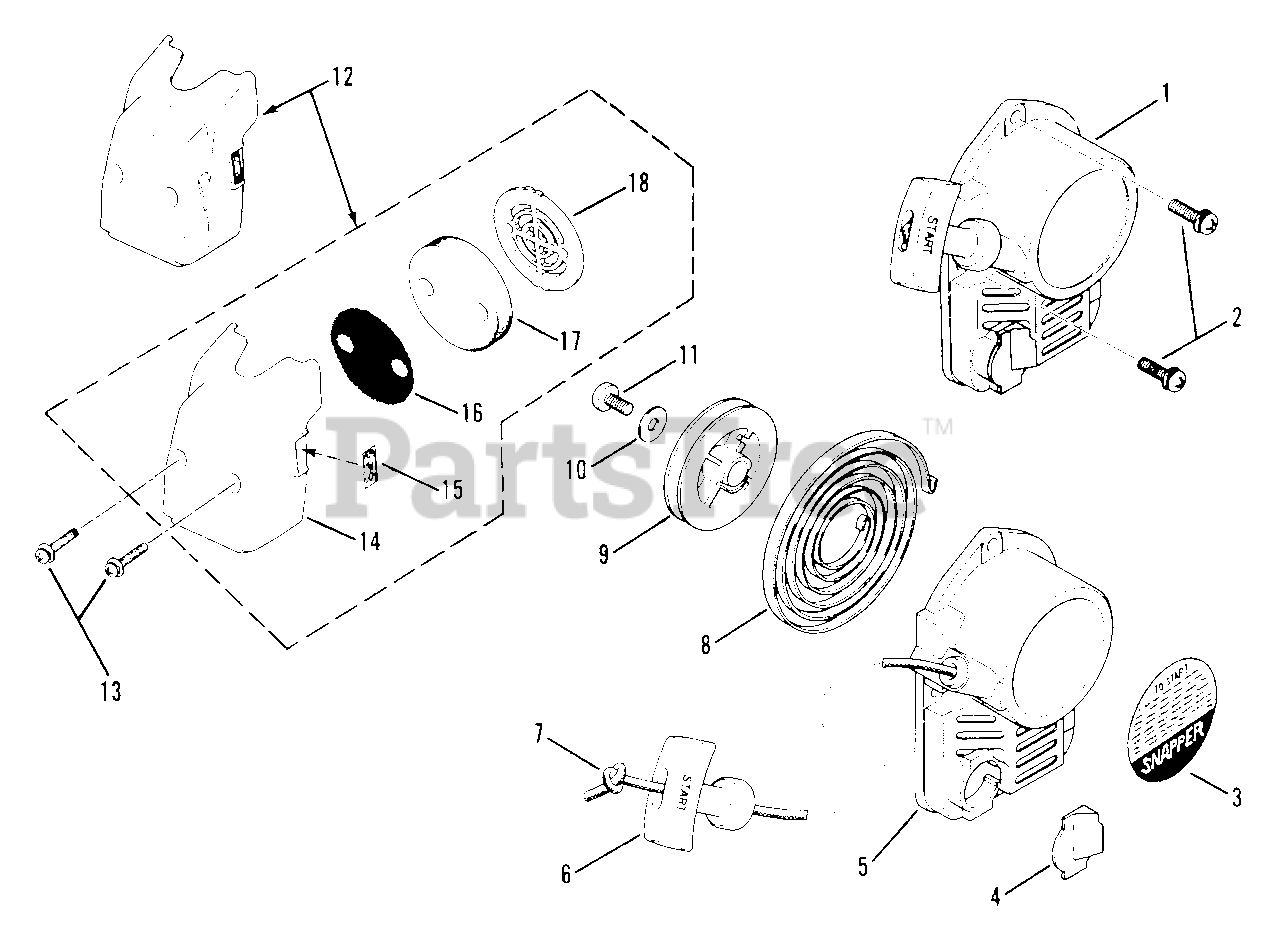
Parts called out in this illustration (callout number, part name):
1	RECOIL STARTER ASSM'Y.
2	SCREW/WASHER
3	DECAL, Starting
5	HOUSING, Starter
6	KNOB, Starter
7	ROPE, Starter
8	SPRING, Spiral
12	AIR CLEANER ASSM'Y.
13	SCREW/WASHER, M4 x 25mm
14	COVER, Air Cleaner
15	NAMEPLATE, Choke
17	ELEMENT
18	HOLDER, Element
